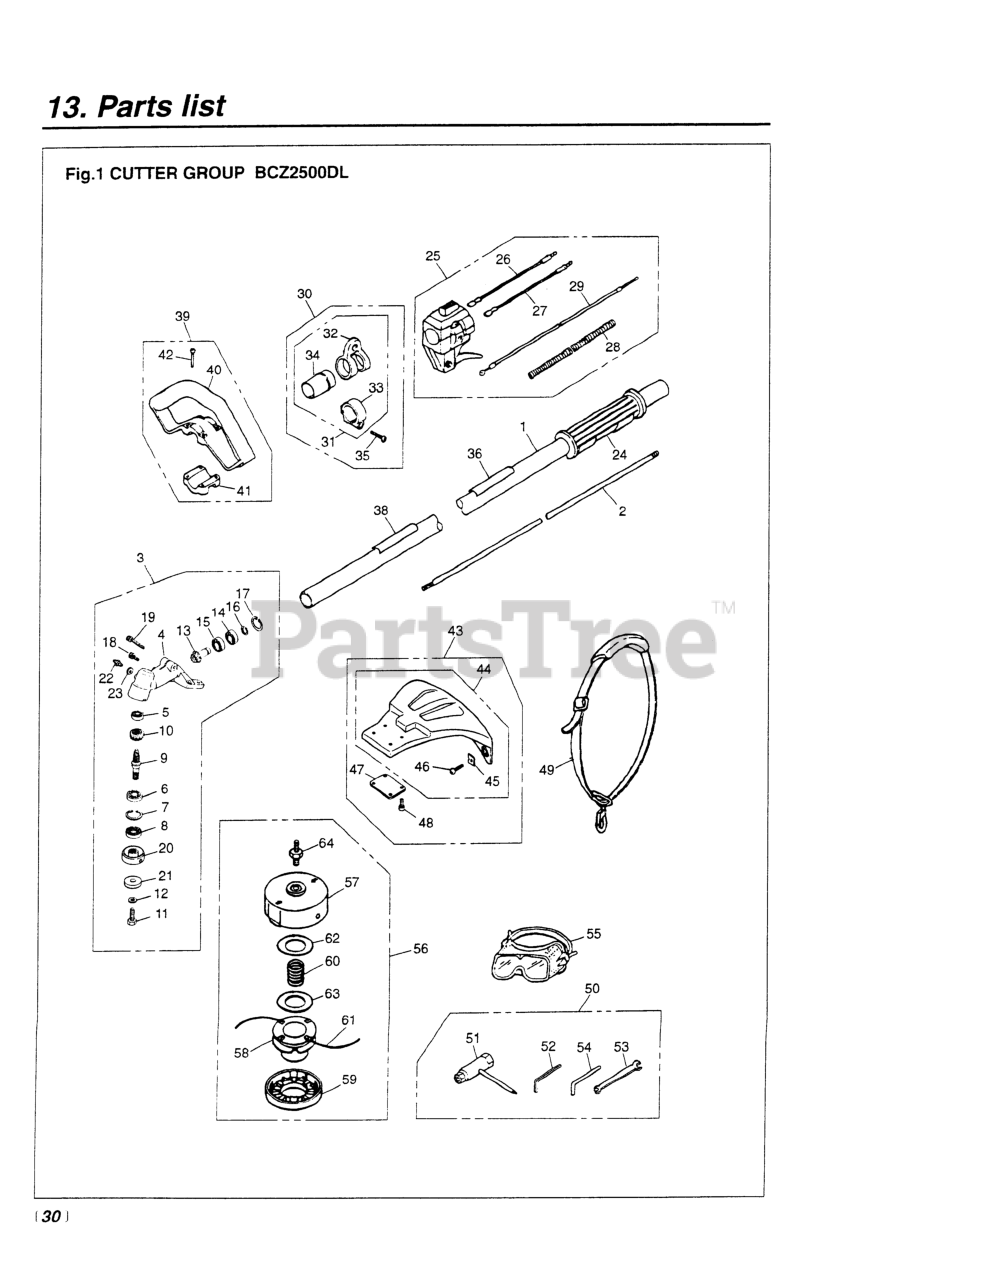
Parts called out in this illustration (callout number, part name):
4	GEARCASE
5	BEARING (RPLS T3300-13521)
6	BEARING (RPLS T3403-13510)
7	RING, SNAP, M26 X 1.2
8	SEAL, OIL
10	GEAR
11	BOLT
12	WASHER
13	PINION
14	BEARING (RPLS T3300-13531)
15	BEARING (RPLS T3403-13530)
16	RING, SNAP (RPLS T3300-13330)
17	RING, SNAP, M24 x 1.2
18	BOLT, M5 X 10
19	BOLT
20	HOLDER (A)
21	SPACER
22	FITTING, GREASE
23	WASHER, M6 X .8
24	GRIP (RPLS 3577-32140 & 3220-
26	CORD (A), BLACK
27	CORD (B), RED
28	TUBE (RPLS 4900-72141)
29	CABLE (RPLS 5580-83100)
30	HANGER ASSEMBLY
31	HANGER COMPLETE
32	HANGER
33	CLAMP
34	SLEEVE
36	PLATE, NAME (BCZ2500S)
38	PLATE, CAUTION
39	HANDLE ASSEMBLY
40	HANDLE
47	PLATE
48	BOLT (USE 3310-31720)
51	SOCKET
52	WRENCH (TOOL)
53	SPANNER, 8 X 10 (RPLS 2540- )
54	BAR
55	GOGGLE
56	PT104
57	CASE (RPLS -15112)
58	HOLDER, CORD (RPLS -15141)
59	COVER (RPLS -15130)
60	SPRING (RPLS -99161)
61	CORD
62	PLATE, LARGE
63	PLATE, SMALL
64	SHAFT
